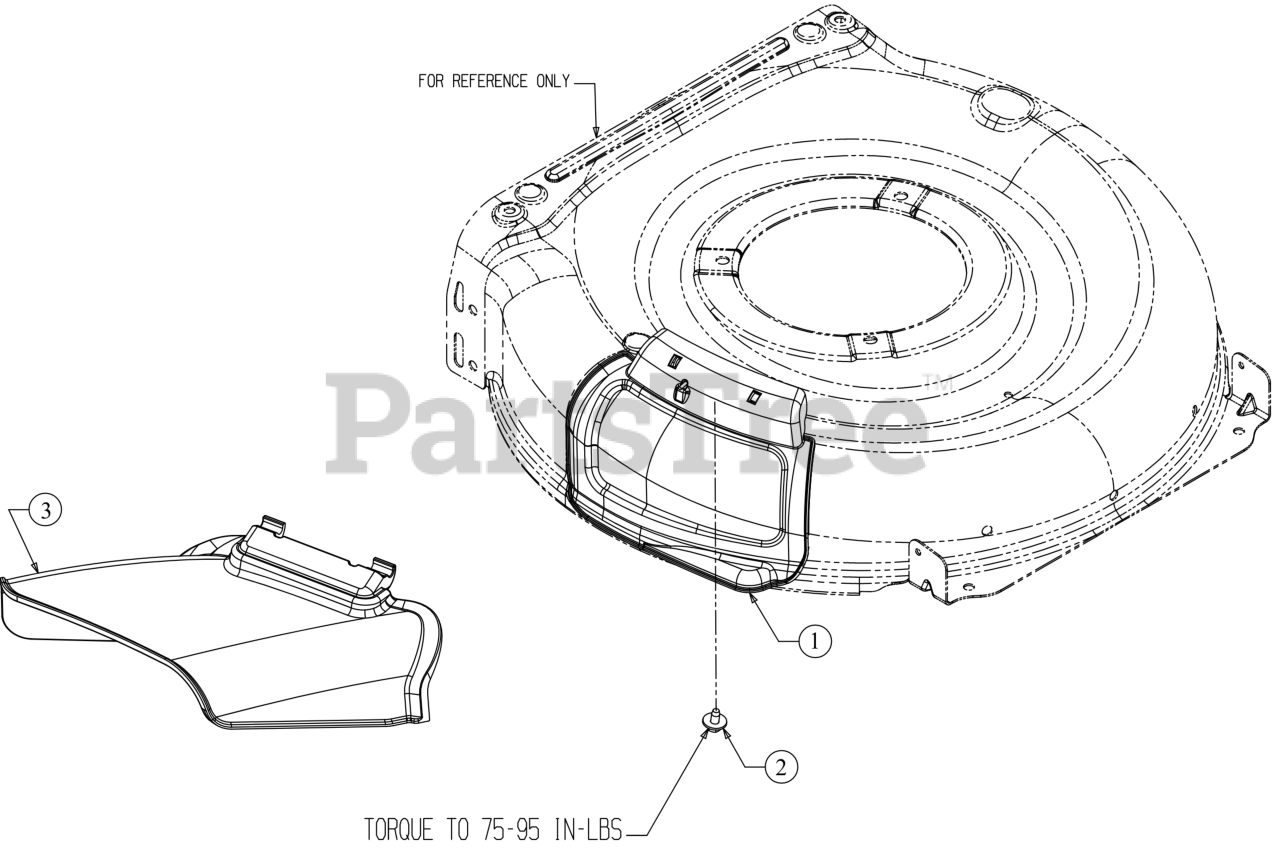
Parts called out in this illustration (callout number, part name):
1	HINGED MULCH PLUG ASSEMBLY
2	SCREW 1/4-20 x .50
3	SIDE DISCHARGE CHUTE
